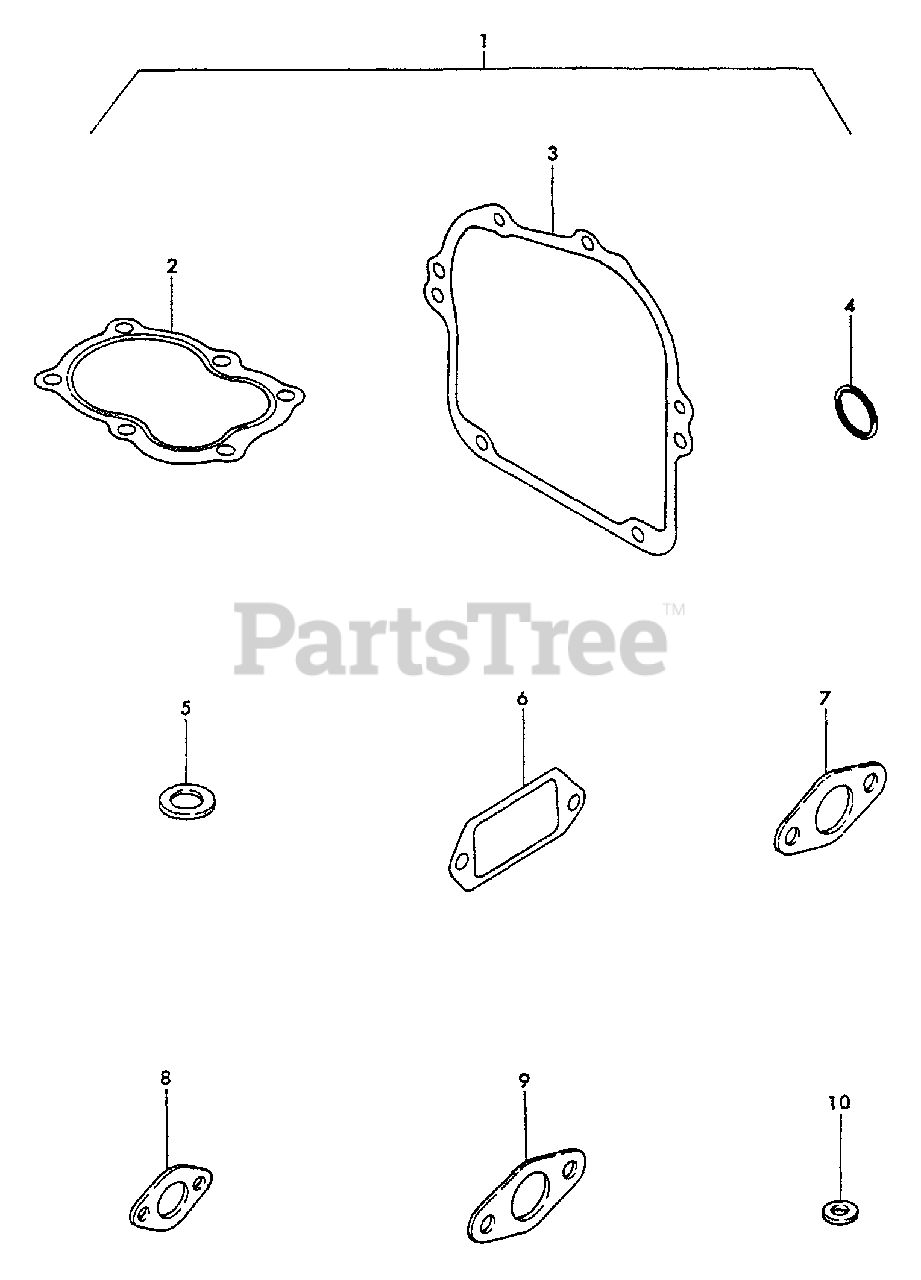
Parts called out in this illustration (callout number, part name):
1	GASKET KIT
2	GASKET, CYLINDER
3	GASKET, CRANKCASE
4	O-RING - 18
5	GASKET
6	GASKET, TAPPET
7	GASKET, INTAKE
8	GASKET, EXHAUST
9	GASKET, INTAKE
10	WASHER - 6 -- NYLON
